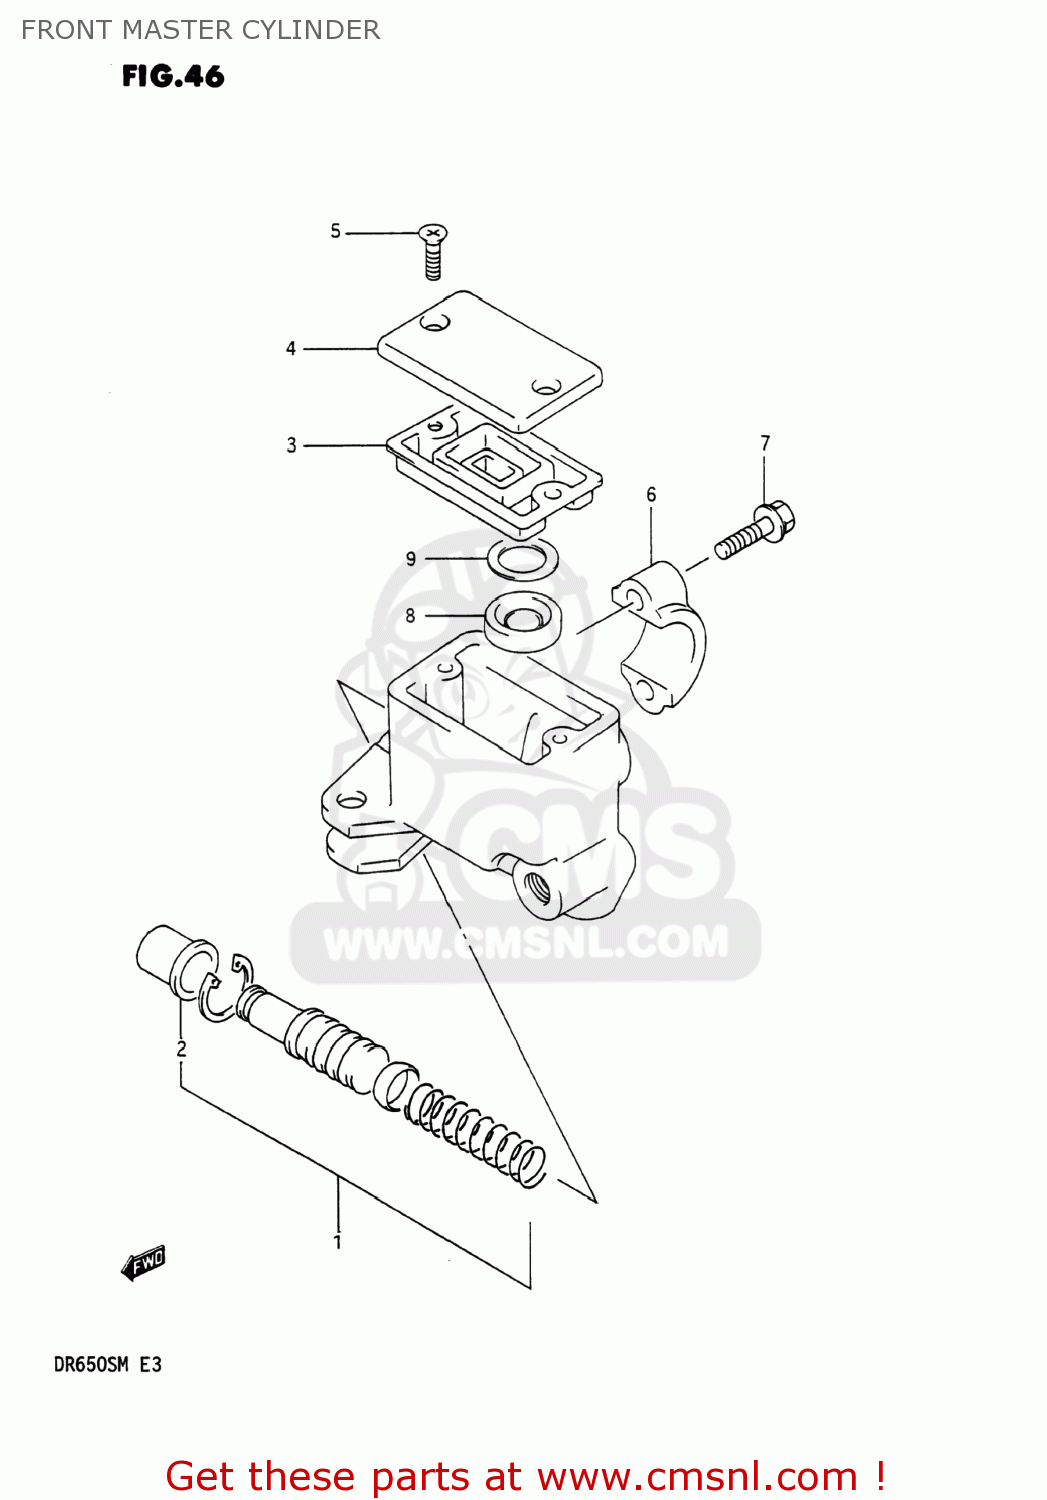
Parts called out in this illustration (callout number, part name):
1	PISTON & CUP SET
2	BOOT
3	DIAPHRAGM
4	CAP
5	SCREW
6	HOLDER
7	BOLT
8	SEPERATOR
9	PLATE
